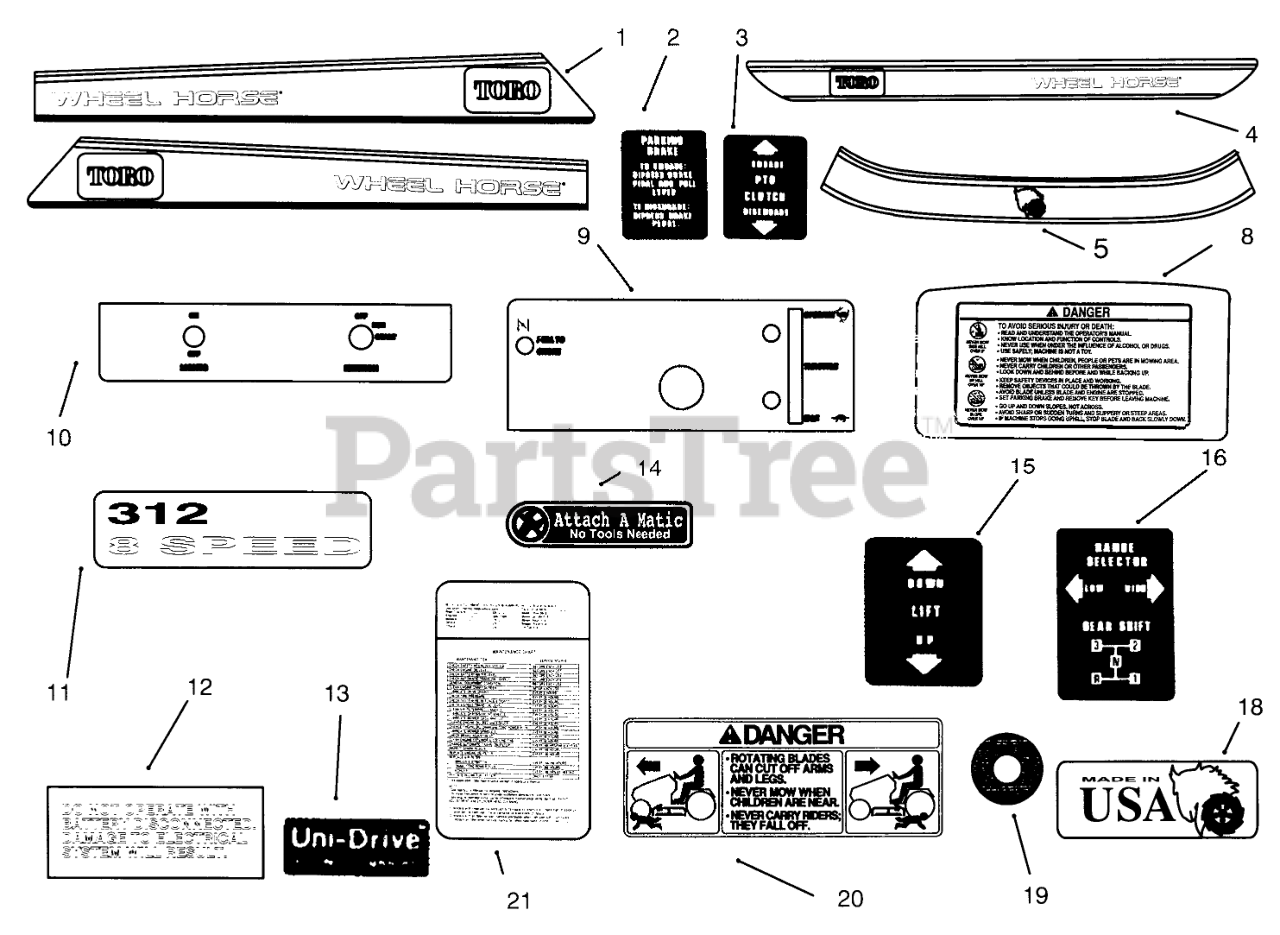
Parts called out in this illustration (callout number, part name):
1	DECAL - RH HOOD TOP
2	DECAL-PARKING, BRAKE
3	DECAL PTO CLUTCH
4	DECAL - REAR FENDER
5	DECAL-FRONT HOOD, TOP
8	DECAL - DANGER
9	DECAL-CONSOLE
10	DECAL-BACK PLATE
11	DECAL - MODEL 312-8
12	DECAL ELECT SYSTEM
13	Decal-Unidrive
14	DECAL-ATTACH A-MATIC
15	DECAL-LIFT
16	DECAL-SHIFT PATTERN
18	DECAL - USA
19	Decal-Air Cleaner
20	DECAL-DANGER
21	Decal-Maintenance
